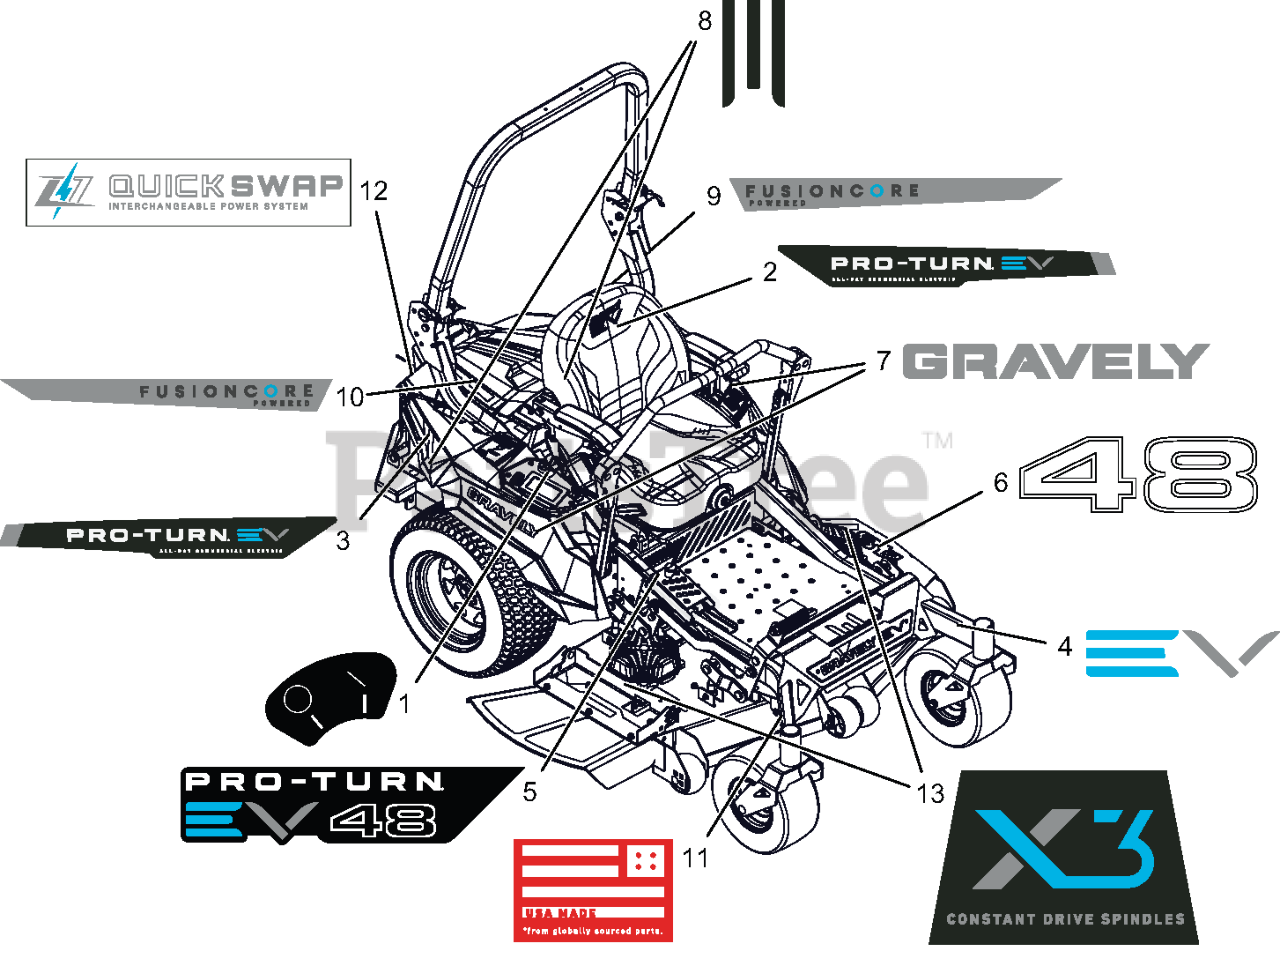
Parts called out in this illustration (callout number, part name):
1	DECAL, KEY SWITCH - 2POS
2	DECAL, FENDER - LH
3	DECAL, FENDER - RH
4	DECAL, FRONT FORK
5	DECAL- KICKER PLATE-48"
6	DECAL, DECK - 48"
7	DECAL, GRAVELY LOGO
8	DECAL, STRIPE
9	DECAL, FUSION CORE - LEFT
10	DECAL, FUSION CORE - RIGHT
11	DECAL, USA MADE
12	DECAL, QUICK SWAP -HATCH
13	DECAL, DECK MOTOR
